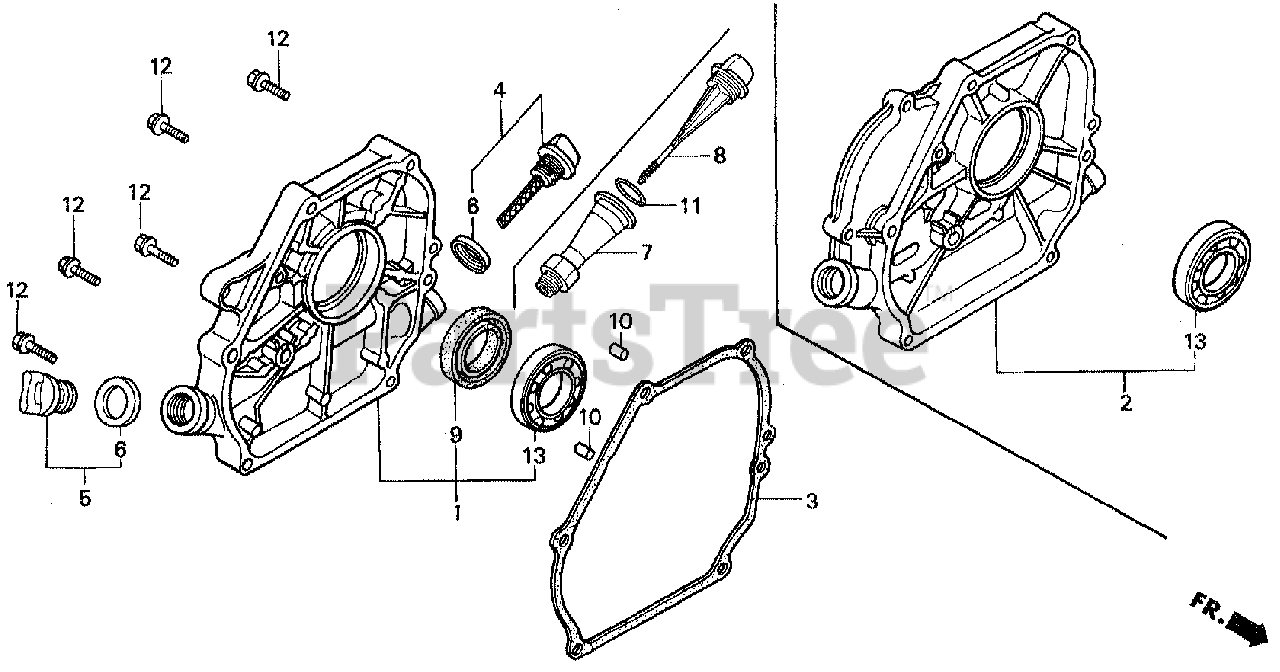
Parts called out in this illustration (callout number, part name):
1	COVER ASSY., CRANKCASE (U-TYPE)
3	GASKET, CASE COVER (NON-ASBESTOS)
4	CAP ASSY., OIL FILLER
5	CAP ASSY., OIL FILLER
6	GASKET, OIL FILLER CAP
9	OIL SEAL (25X41X6)
10	PIN A, DOWEL (8X14)
12	BOLT, FLANGE (8X32)
13	BEARING, RADIAL BALL (6205)
